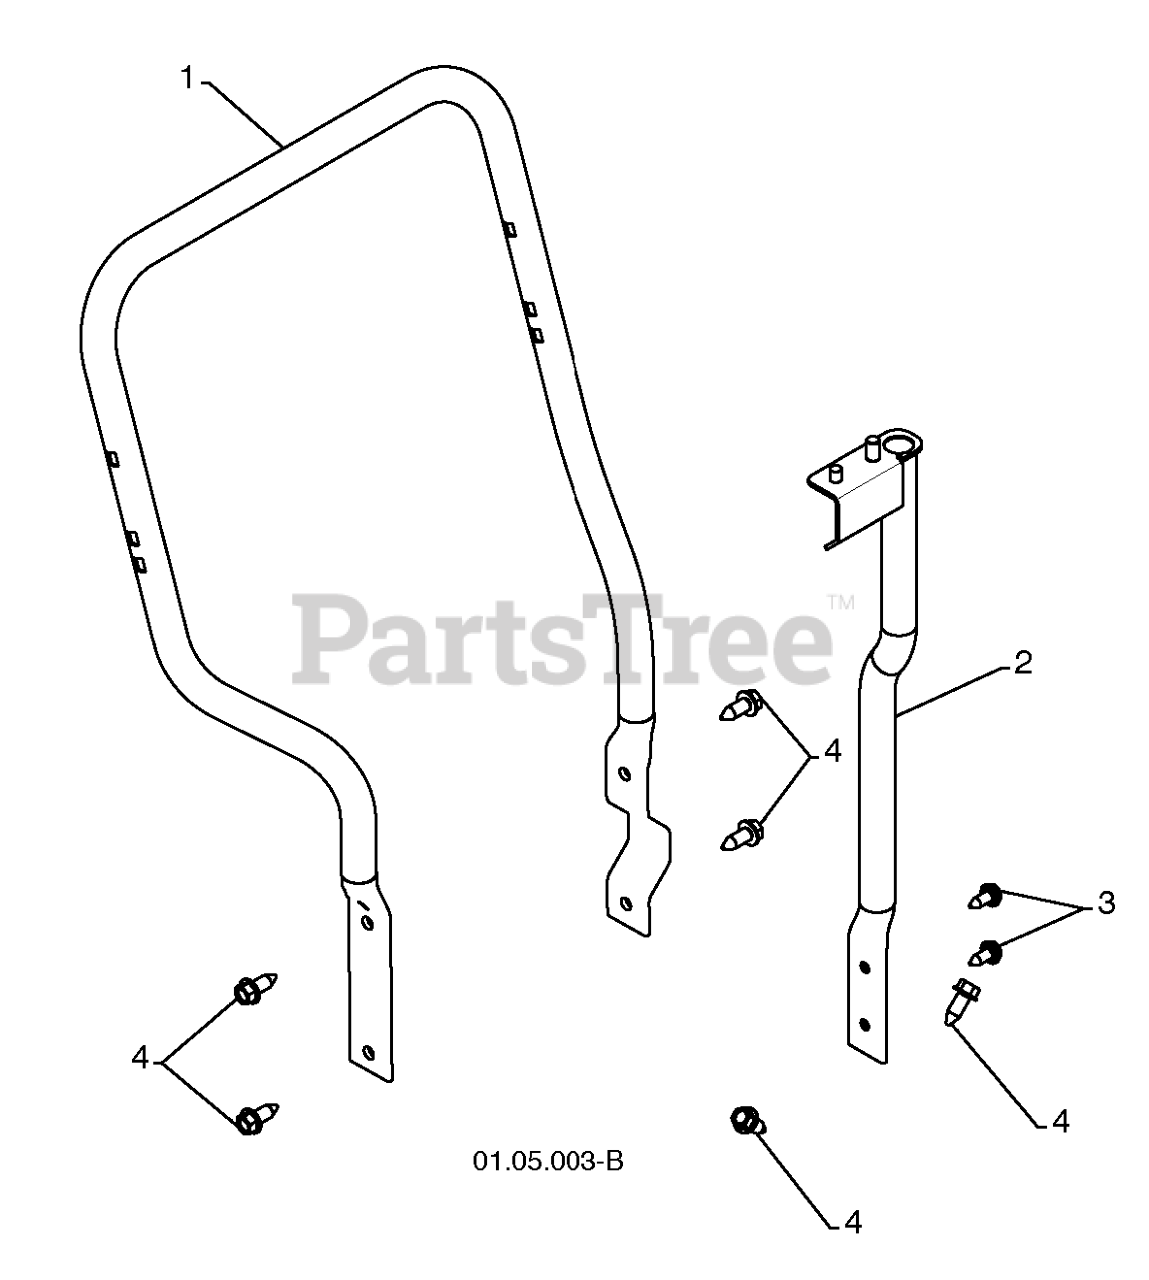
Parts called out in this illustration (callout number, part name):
1	TUBE.LOWER.HANDLE.SNOW.BLACK
2	SUPPORT.WELDMENT.ROTATOR.
3	SELF-TAPPING SCREW 5/16-18X3/4
4	SCREW 3/8-16X1
